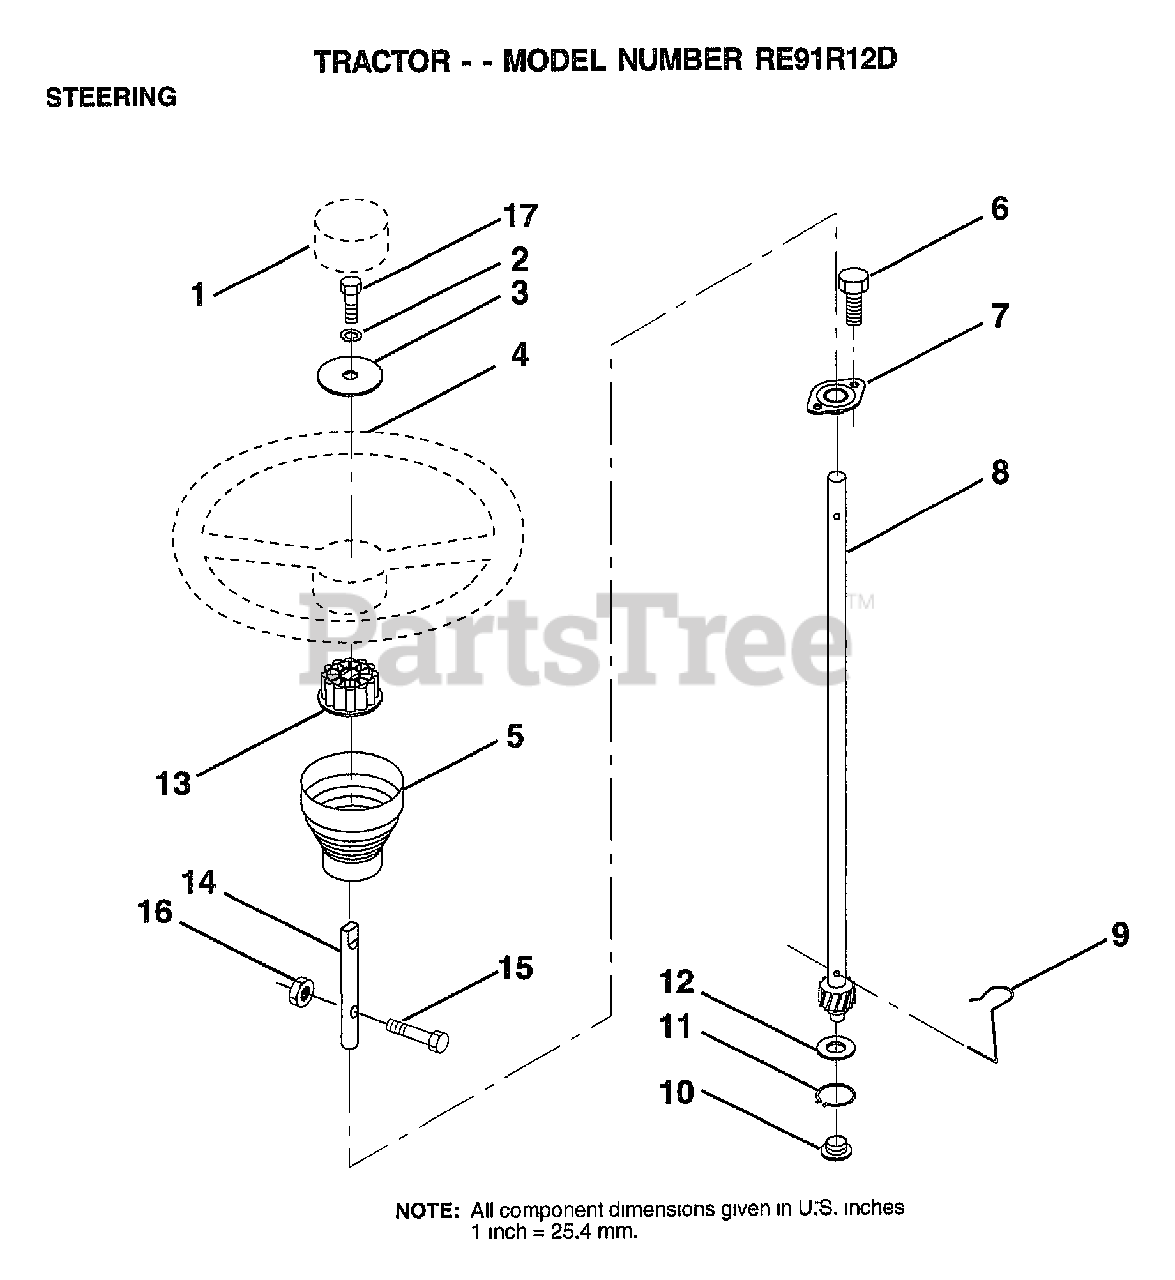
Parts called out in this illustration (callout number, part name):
1	ST WHL INSERT CAP
2	LOCKWASHER
3	WASHER
5	SLEEVE STEERING
6	"SCREW-TT,10-32 FL"
7	BUSHING.STR.623
8	SHAFT.STEERING.LR
9	STEERING CLIP
10	BUSHING STEER LWR
11	RING
12	WASHER LT
13	ADAPTER LT
14	EXT SHAFT STEERIN
15	BOLT
16	NUT
17	BOLT
